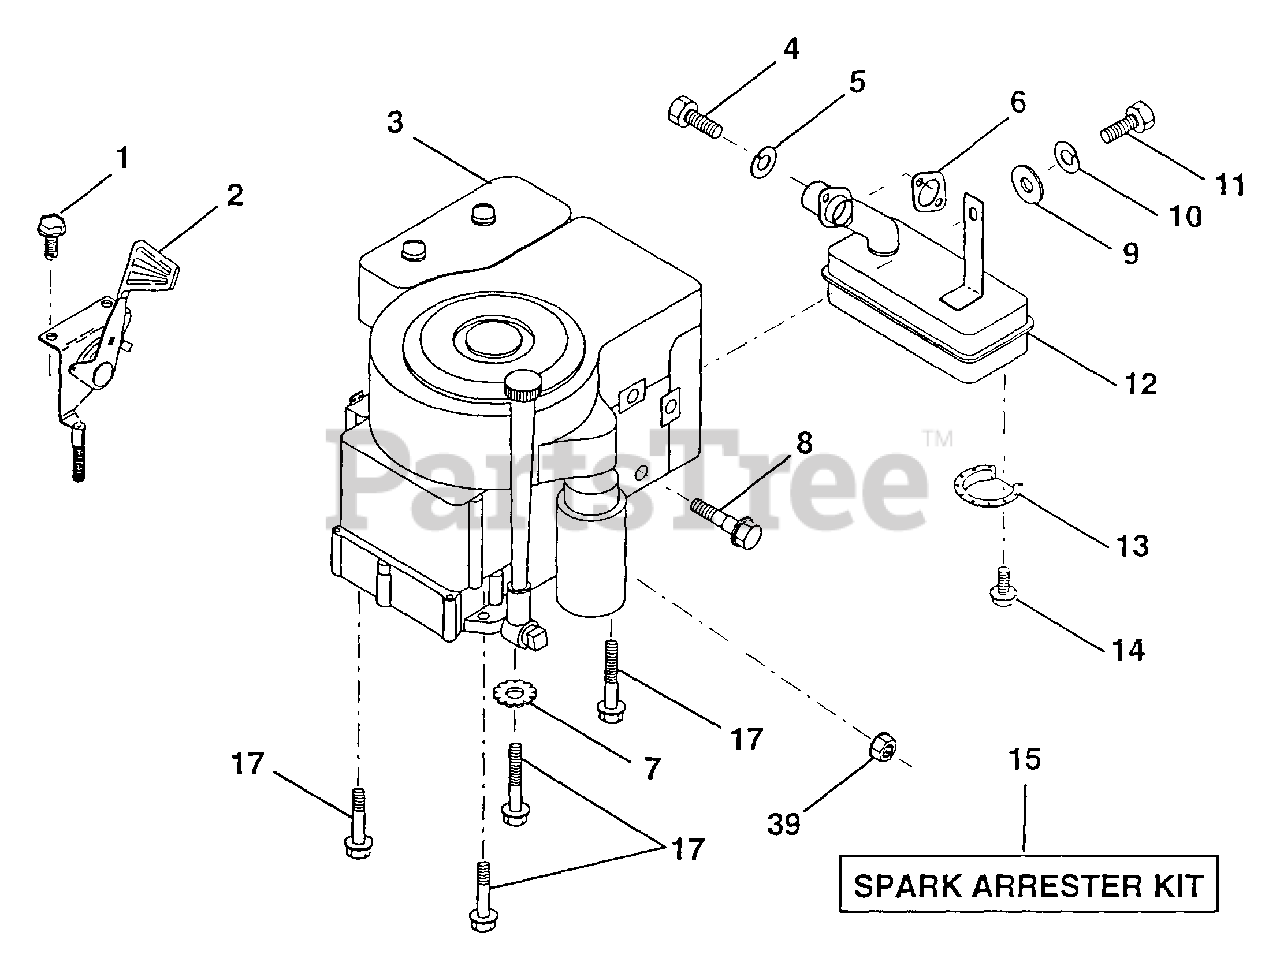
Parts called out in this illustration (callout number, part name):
1	Screw, Hex Thd. Cut 1/4-20 x 1/2
2	Control, Throttle
3	Engine, Briggs & Stratton
4	Screw, Hex, Cap 5/16-18 x 3/4
5	Washer, Lock Heavy Helical Spring 5/16
6	Gasket, Exhaust
7	Washer, Lock Ext. Tooth 3/8
8	Bolt, Shoulder 5/16
9	Washer 5/16 x 3/4 x 16
10	Washer, Lock Hvy Hlcl Spring 1/4
11	Bolt, Hex Fin.
12	Muffler
13	Deflector, Muffler
14	Screw, Spiderloc Hex Hd #8 x 1/2 (AYP part number)
15	Arrester, Spark
17	Screw, Hex Washer Head, Thdrol. 3/8-16 x 1-1/2
39	Nut, Flange 1/4-20
